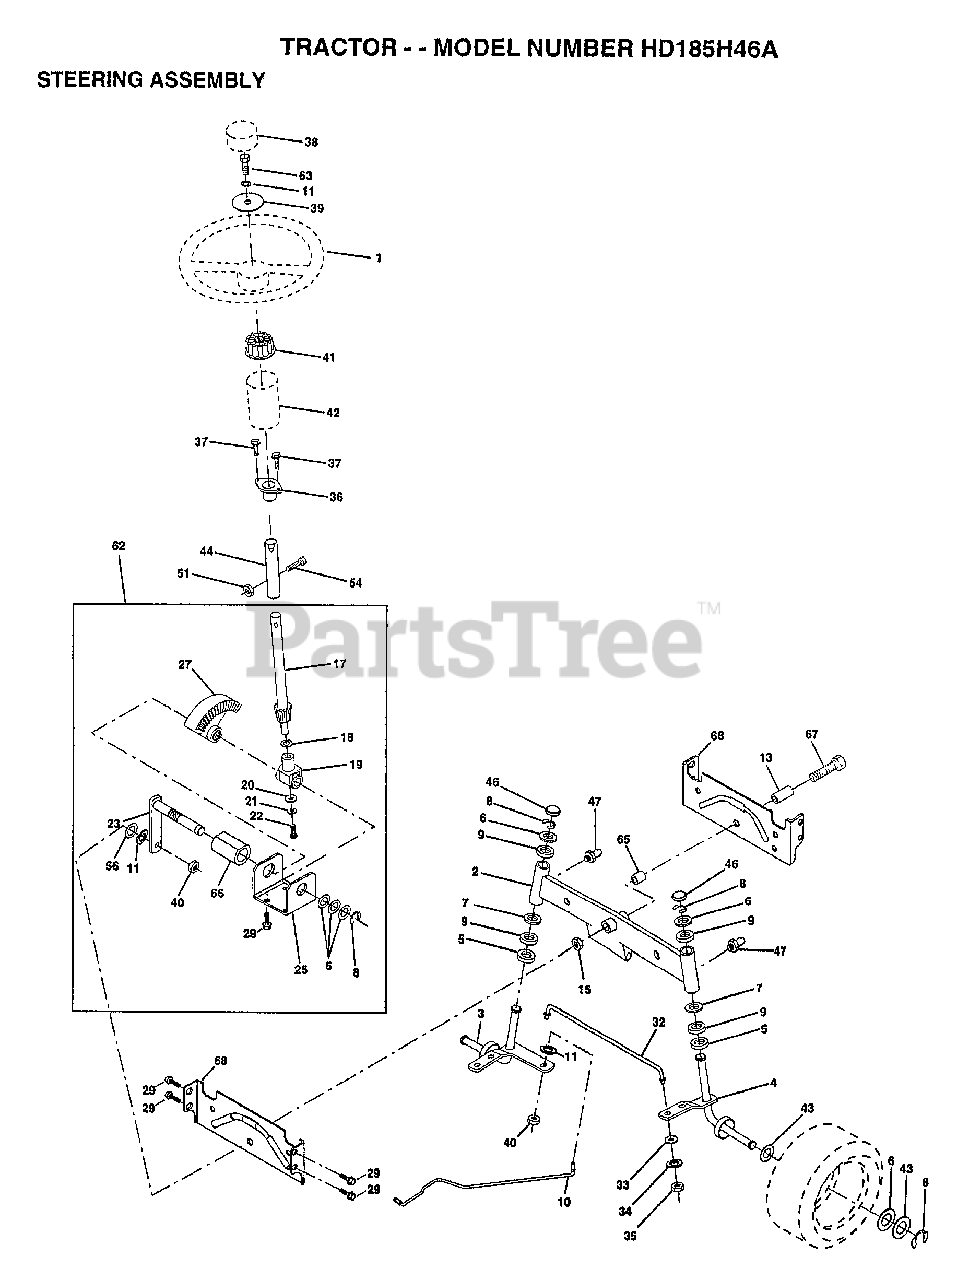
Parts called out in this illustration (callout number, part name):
1	WHEEL STR AYP BLK
2	AXLE ASM
3	"SPINDLE ASM, LH"
4	SPINDLE ASM RH
5	WASHER .T
6	WASHER
7	WASHER
8	RING
9	COL. SRTG. BEAR.
10	DRAGLINK-STAMPED
11	LOCKWASHER
13	BEARING AXLE
15	"NUT-LOC,FLANGE LT"
17	SHAFT ASM STEERIN
18	THRUST WASHER
19	SUPPORT.SHAFT
21	LOCKWASHER
22	SCREW.SCKTHD.CAP
25	BRKT-STEERING
27	GEAR SECTOR
29	SCREW
32	ROD.TIE.19.75
33	WASHER M
34	LOCKWASHER
35	NUT.LOCK.5/16-24
36	BUSHING.STEERING
37	"SCREW-TT,10-32 FL"
38	CAP STEER AYP
39	WASHER T
40	GRIPCO NUT
41	ADAPTER LT
42	BOOT.STEER.PL
43	WASHER
44	EXT SHAFT STEERIN
46	CAP
47	ZERK M
51	NUT
54	BOLT
56	WASHER
62	KIT STEERING ASM
63	BOLT
65	SPACER AXLE
66	"BEARING-ARM,PITMA"
67	BOLT
68	BRACE AXLE
